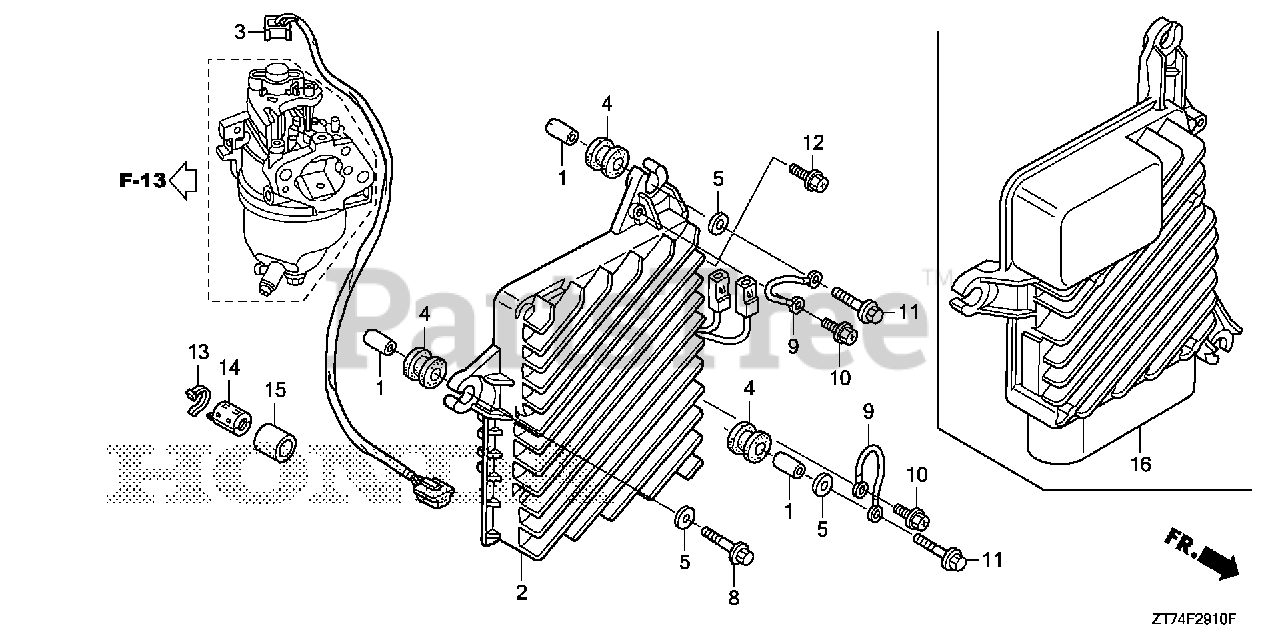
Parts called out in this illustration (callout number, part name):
1	COLLAR, IN. JOINT
2	INVERTER UNIT (NOT AVAILABLE, USE KIT 06310-ZS9-R30)
3	SUB-WIRE ASSY.
4	RUBBER, INVERTER UNIT
5	WASHER, PLAIN (6MM)
8	BOLT, FLANGE (6X25)
11	BOLT, FLANGE (6X25)
